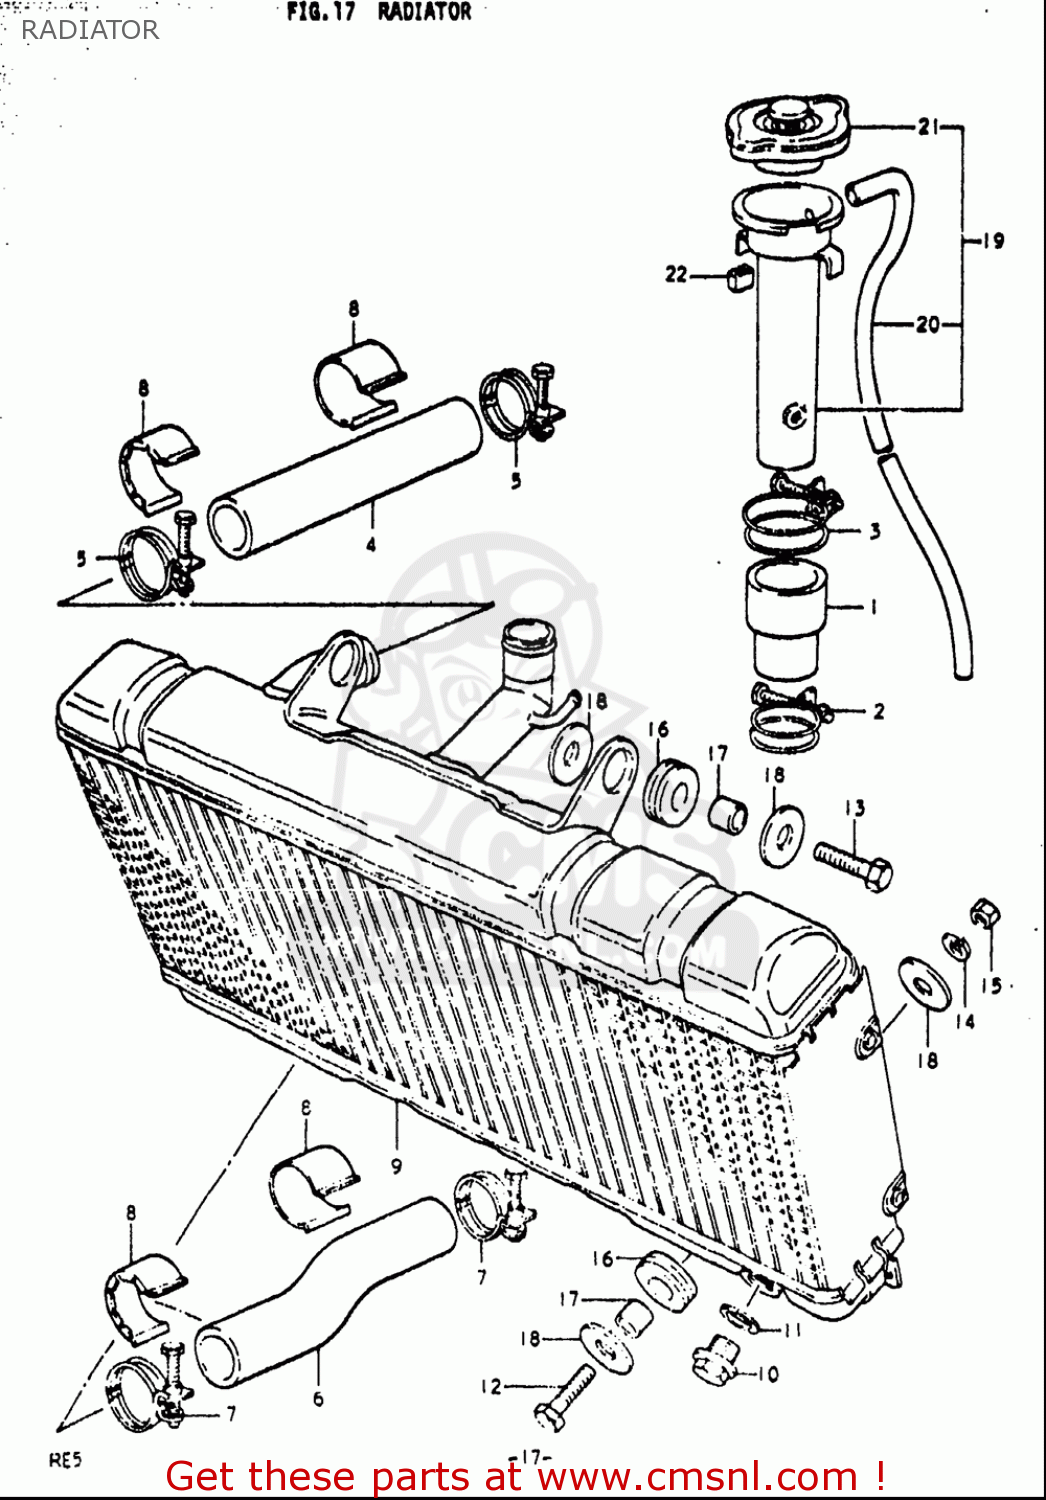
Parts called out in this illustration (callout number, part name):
2	CLAMP
3	CLAMP
5	CLAMP
7	CLAMP
12	BOLT
13	BOLT
14	WASHER,LOCK
15	NUT
16	CUSHION
17	SPACER,8.5X14X9
21	CAP,RADIATOR 0.9
22	CUSHION
